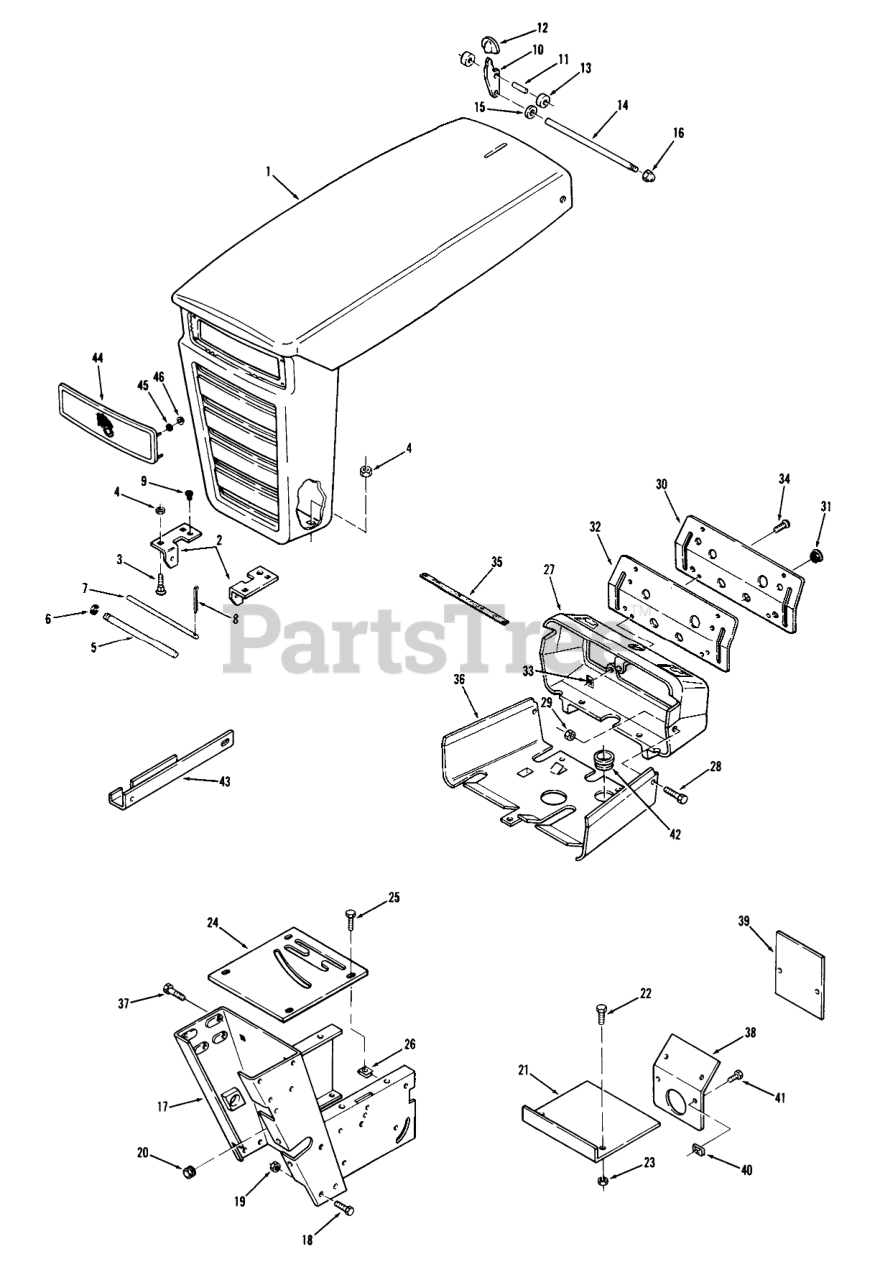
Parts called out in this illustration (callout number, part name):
1	Hood
2	Bracket-Grille-L.H.
2	GRILL PIVOT BRKT
3	Bolt
4	Nut
5	GRILL PIVOT ROD
6	RING-RETAINING
7	ROD-HOOD STOP
8	Cotter Pin
9	GROMMET
10	LEVER HOOD LATCH
11	SPIROL PIN
12	KNOB
13	Roller
14	Rod Latch
15	SPEED NUT
17	Hoodstand Assy
18	BOLT
19	Nut
20	Bushing
21	Cover-Dust
22	Bolt
23	Nut
24	Cover Plate
25	Screw
26	Speed Nut
27	Housing
28	Screw
29	Nut
30	Dash Panel
30	Dash Panel (B-60)
31	PLUG BUTTON
32	BACK UP PLATE
33	SPEED NUT
34	SCREW BLACK
35	Tape
36	Support-Tank
37	Screw
38	Instrument Backet
39	Plate Cover Hoodstand
40	Speed Nut
41	Screw
42	Grommet
43	Channel
44	ESCUTCHEON PLATE
45	WASHER
46	SPEED NUT
